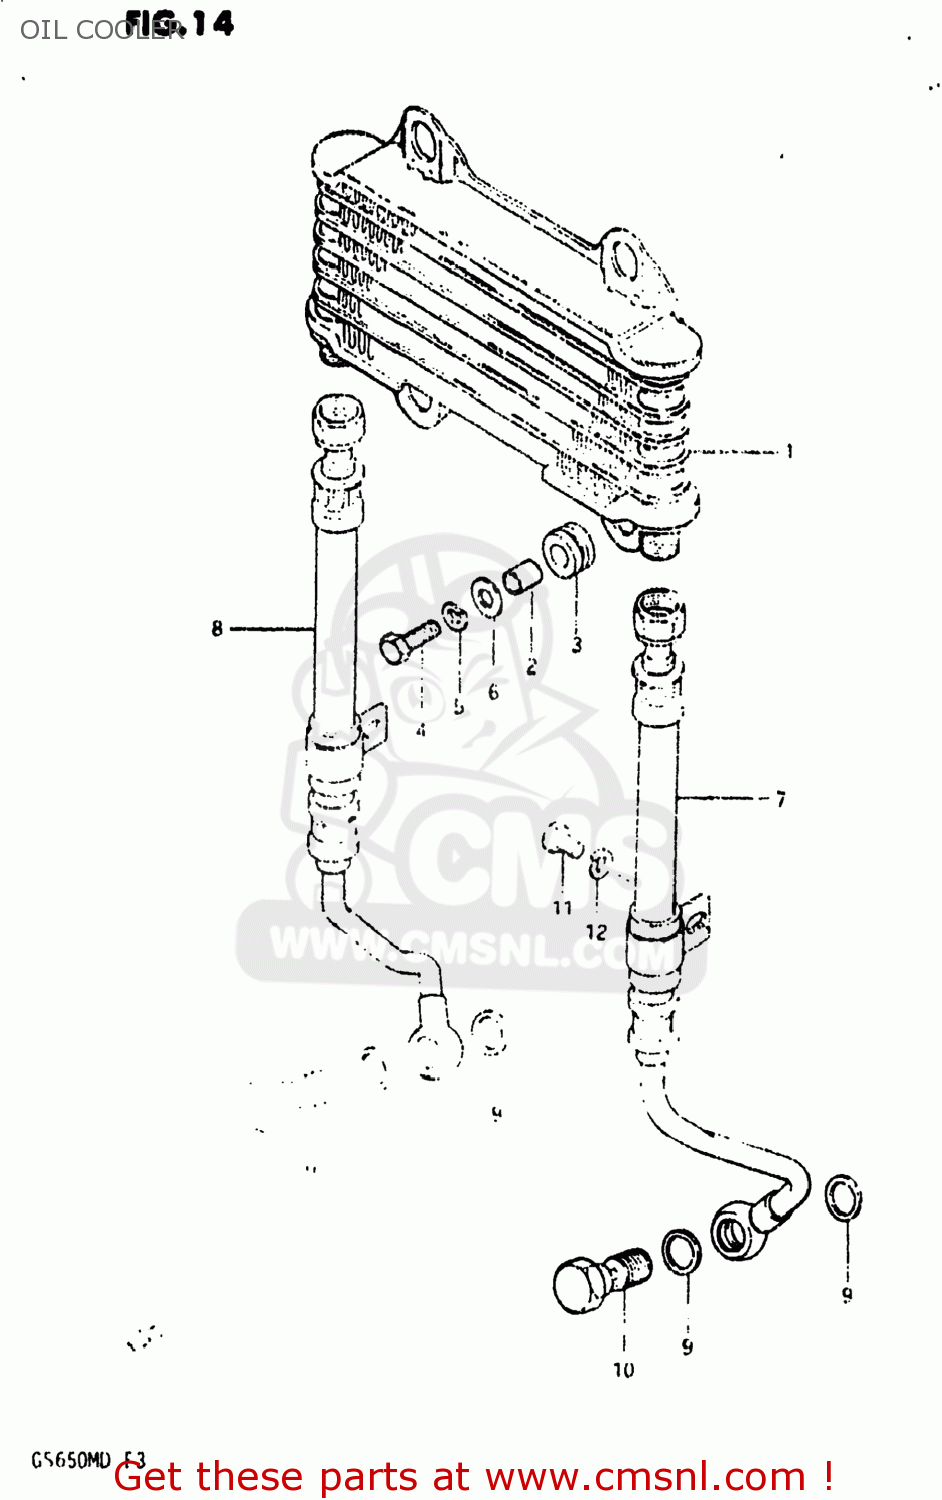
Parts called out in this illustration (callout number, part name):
1	COOLER ASSEMBLY,ENGINE OIL
2	SPACER (6.8X10X10)
3	CUSHION
4	BOLT
5	LOCK WASHER
6	WASHER (6.5X18X1.6)
7	HOSE,ENGINE OIL,RIGHT
8	HOSE,ENGINE OIL,LEFT
9	GASKET(14X20X1.5) (NAS)
10	BOLT UNION
11	BOLT
12	LOCK WASHER
